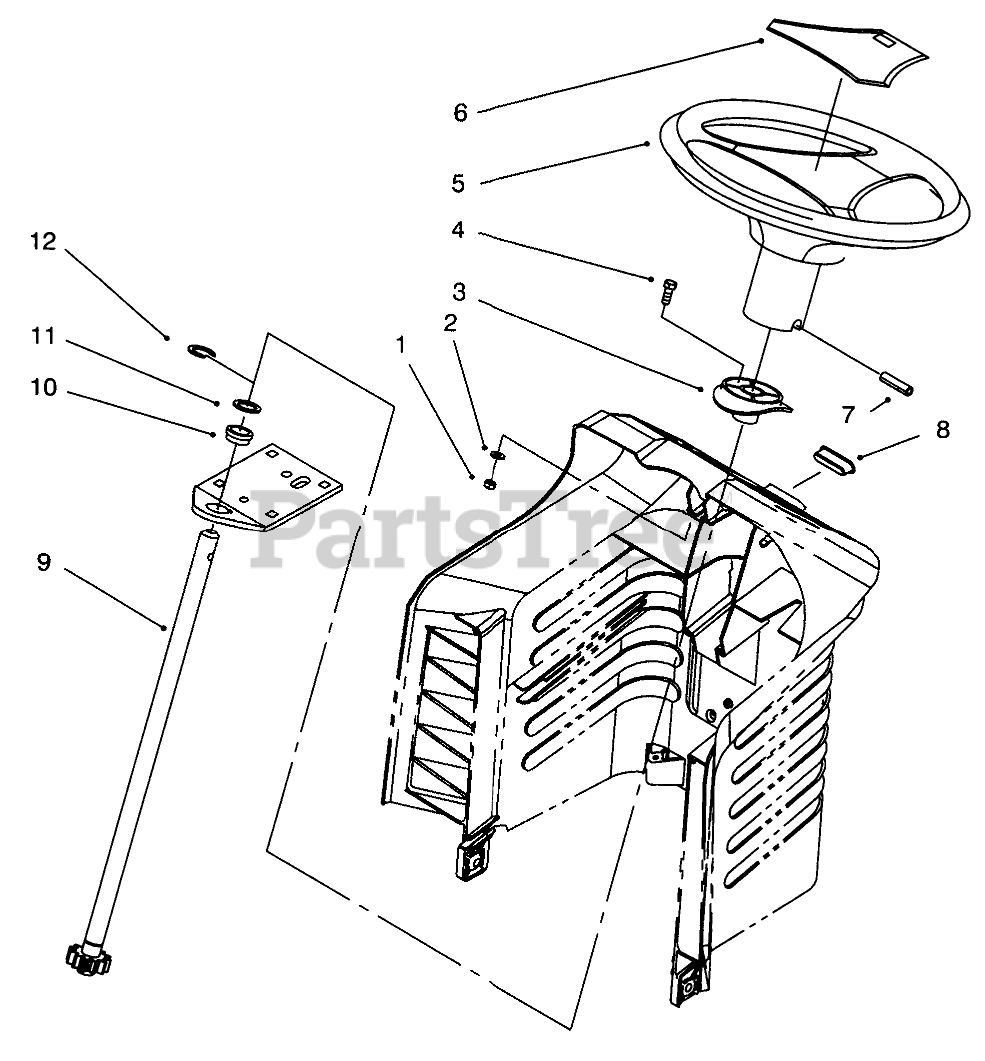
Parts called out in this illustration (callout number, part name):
1	NUT-LOCK, NI
2	WASHER-FLAT
3	BUSHING-SLIDING
4	SCREW-HH
5	Wheel-Steering (Incl. Ref. #6)
6	COVER-WHEEL
7	PIN-ROLL
9	SHAFT-STEERING, LONG
10	BEARING-FLANGE
11	WASHER-THRUST
12	E-RING
